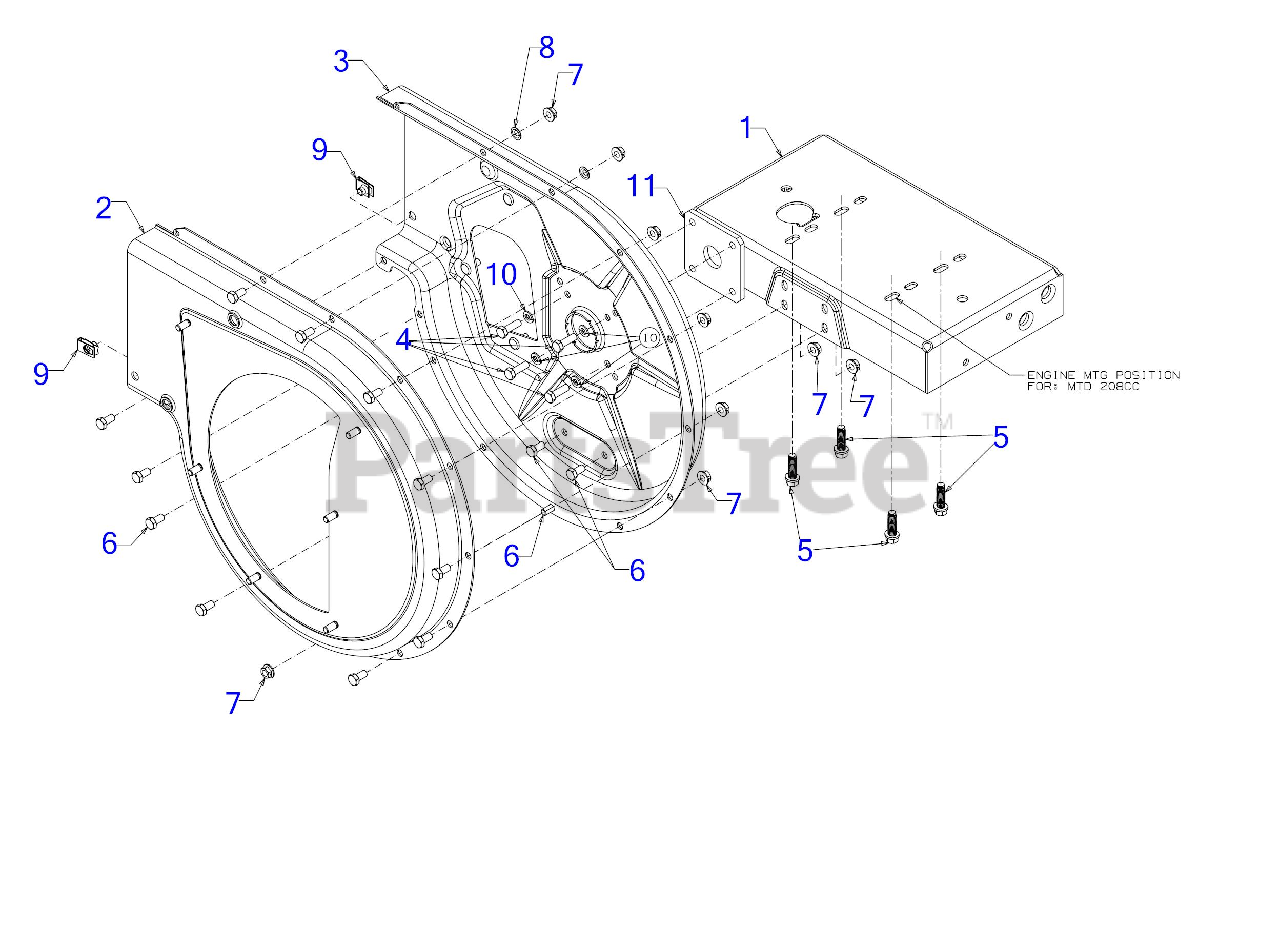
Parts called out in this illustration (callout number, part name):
1	FRAME ASSEMBLY
2	FLAIL HOUSING ASSEMBLY (OUTER)
3	INNER FLAIL HOUSING
4	HEX HEAD CAP SCREW 5/16-24 x 1.00 GR5
5	SCREW 3/8-16 x 1.250
6	SCREW 5/16-18X .625 GR5
7	HEX FLANGE NUT
9	U-NUT
10	LOCK WASHER 5/16
